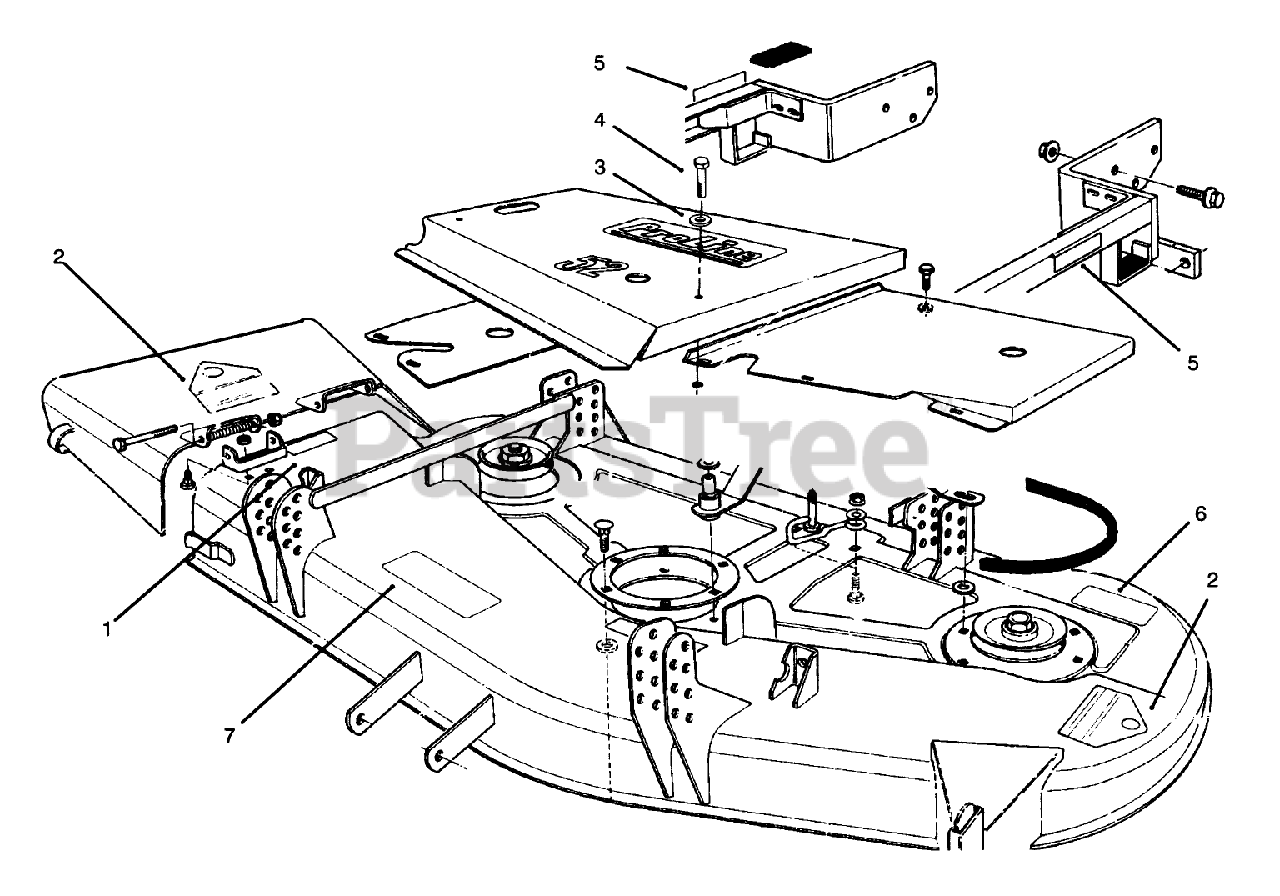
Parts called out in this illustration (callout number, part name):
1	DECAL - WARNING
2	DECAL-DANGER
3	WASHER-FLAT
4	SCREW-HH
5	DECAL-HOC
6	DECAL-TORQUE, BLADE BOLT
7	DECAL-DANGER
